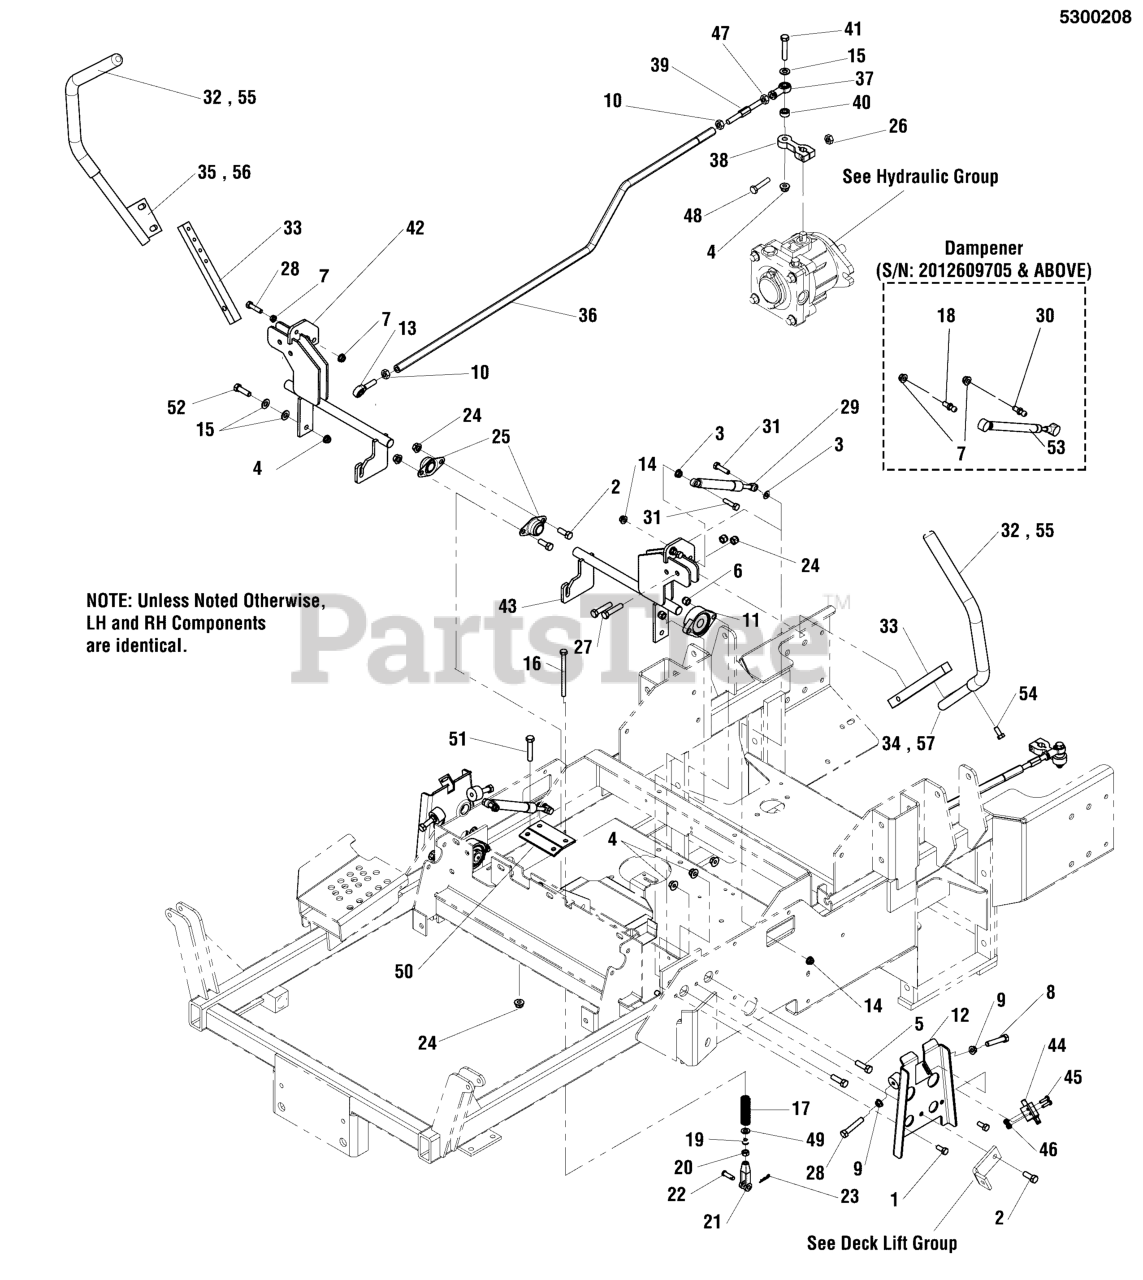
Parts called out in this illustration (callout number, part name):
1	BOLT, 5/16-18 X 3/4 GD5
2	BOLT, 5/16-18 X 1" GD5 YZ
3	NUT, M8-1.25 SERR. FLANGE, CZ
4	NUT, 5/16-18 HEX NYLOCK FLANGE
5	BOLT, 3/8-16 X 1-1/4 SHCS
6	NUT, 3/8-16 HEX NYLON LOCK
7	NUT, 5/16-18 HEX SERRATED FLANGE (LARGE)
8	BOLT, 5/16-18 X 1-3/4 TFL, GD5 YZ
9	NUT, 5/16-18 HEX SERRATED FLANGE (SMALL)
10	NUT, 3/8-24 HEX, LH
11	BEARING, FLANGE
12	WELD,PLATE,NEUTRAL CONTROL
13	BALL JOINT, 3/8-24 MALE
14	NUT, M8-1.25 NYLON LOCK, CZ
15	WASHER, 3/8 SAE
16	BOLT, 5/16-24 X 4.25" GD5 YZ
17	SPRING, REVERSE RETURN
18	BALL STUD 10MM 5/16-18 X 3/4"
19	NUT, 5/16-24 HEX NYLON LOCK
20	NUT, 5/16-24 HEX
21	CLEVIS, 5/16-24, STEEL, CLEAR ZINC
22	PIN, CLEVIS, 5/16" X 1
23	PIN, COTTER, 1/8 X 1-1/4
24	NUT, 3/8-16 HEX NYLOCK FLANGE
25	BEARING, BRONZE FLANGE, 3/4
26	NUT, 1/4-20 HEX NYLOCK FLANGE
27	BOLT, 3/8-16 X 1-3/4" GD5 CZ
28	BOLT, 5/16-18 X 1-1/4" GD5 YZ
29	DAMPENER
30	BALL STUD 10MM 5/16-18 X 1/2"
31	BOLT, M8-1.25 X 35MM, GD8.8
32	GRIP, FOAM, 3/4" ID, 16" LONG
33	MOUNT, CONTROL ARM - BLK
34	WELD, HANDLE MOTION CONTROL, LH - RED
35	WELD, HANDLE MOTION CONTROL, RH - RED
36	CONTROL ROD, IS5000Z
37	ROD END, 3/8-24 LH FEMALE
38	ARM, PUMP CONTROL (21 SERIES)
39	LINK, ADJUSTABLE, SHORT
40	SPACER, .39 X .75 X .38
41	BOLT, 3/8-16 X 2, GD5, CZ
42	WELD, CONTROL SHAFT - RH - RED
43	WELD, CONTROL SHAFT - LH - RED
44	SWITCH, PLUNGER, N.O.
45	SCREW, #10-24 X 3/4" ROUND SLOTTED
46	NUT, #10-24 HEX NYLON LOCK
47	NUT, 3/8-24 HEX
48	BOLT, 1/4-20 X 1-3/4" GD5 YZ
49	WASHER, 5/16" USS
50	PLATE, RETURN TO NEUTRAL - RED
51	BOLT, 3/8-16 X 1" GD5 CZ
52	BOLT, 3/8-16 X 1-1/2" GD5 CZ
53	DAMPENER, CONTROL
54	SCREW, 5/16-18x0.750, GR5, WHIZ-LOCK, ZC
55	GRIP, FOAM, 1" ID, 16" LONG
56	WELD, HANDLE MOTION CNTRL, 15.1, 1.0 - RH - BLK
57	WELD, HANDLE MOTION CNTRL, 15.1, 1.0 - LH - BLK
